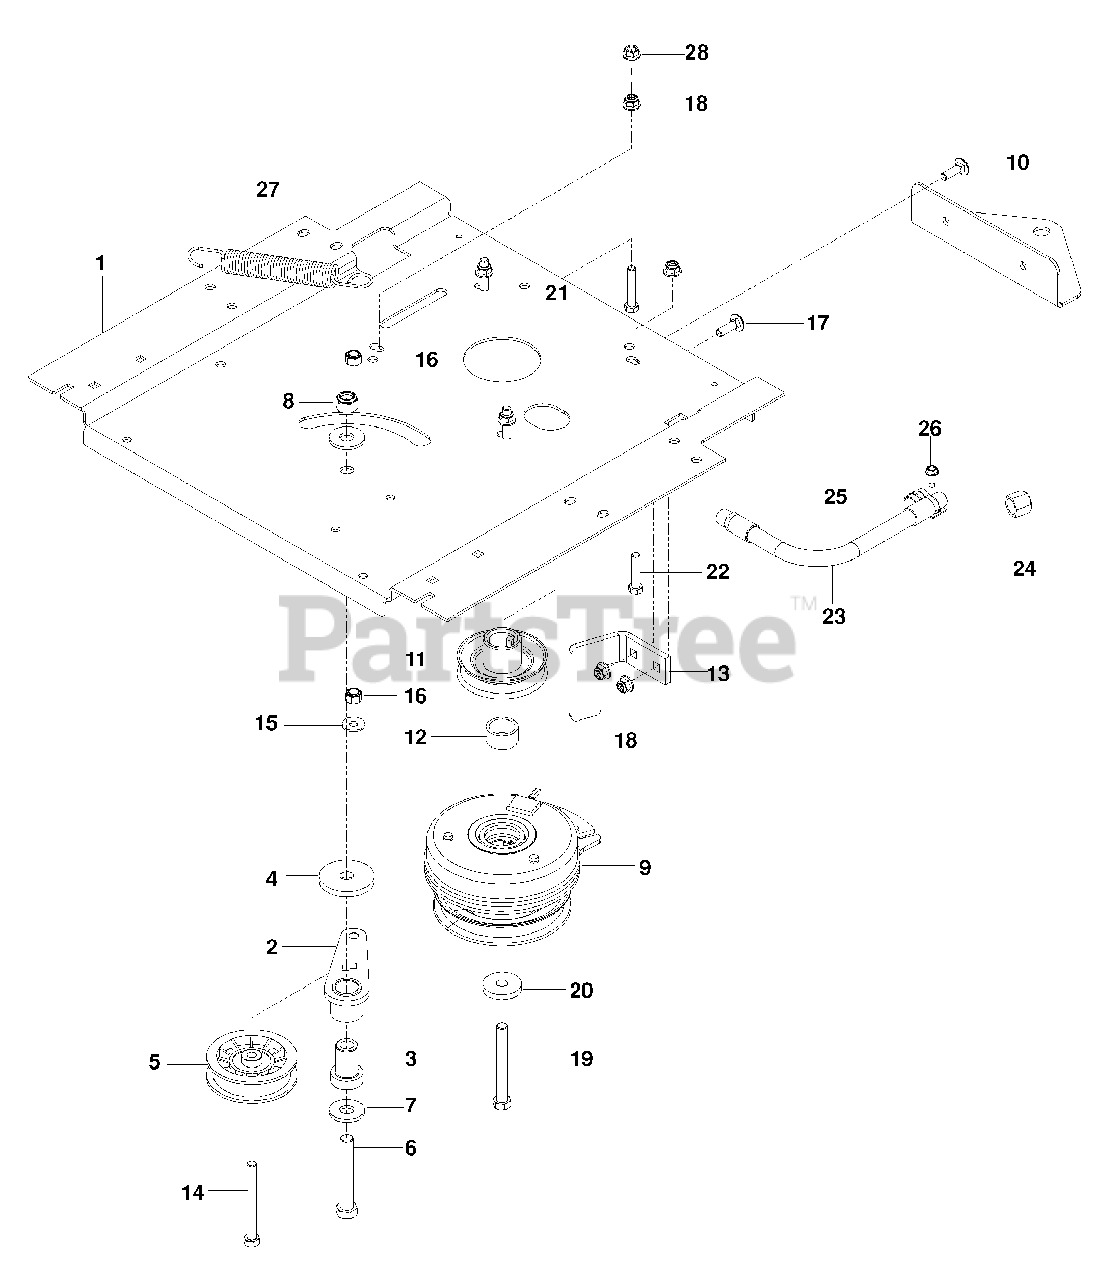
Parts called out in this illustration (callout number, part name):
1	PLATE, ENGINE BLK
2	ARM, IDLER
3	SPINDLE, IDLER
4	WASHER, HEAVY
5	PULLEY, IDLER
6	HCS 1/2-13 x 3 1/4
7	WASHER 1/2 FLT
8	NUT 1/2-13 HEX NYLOC
9	CLUTCH, 105 FT-LBS
10	HITCH, BLK
11	PULLEY, ENGINE
13	STOP, CLUTCH BLK
14	HCS 3/8-16 x 3 1/2
15	WASHER 5/16 STD FLT
16	NUT 3/8-16 HEX NYLOC
17	RHSNB 5/16-18 x 1
18	NUT 5/16-18 FLANGE NYLOC
19	HCS 7/16-20 x 3 1/2
20	WASHER, CLUTCH
21	HCS 5/16-18 x 1 3/4
22	HCS 5/16-18 x 1 1/2
23	HOSE, DRAIN
26	SCREW 1/4-20 x 5/8 SLF TAP
27	SPRING, DECK DRIVE
28	NUT 5/16-18 HEX WHIZLK
